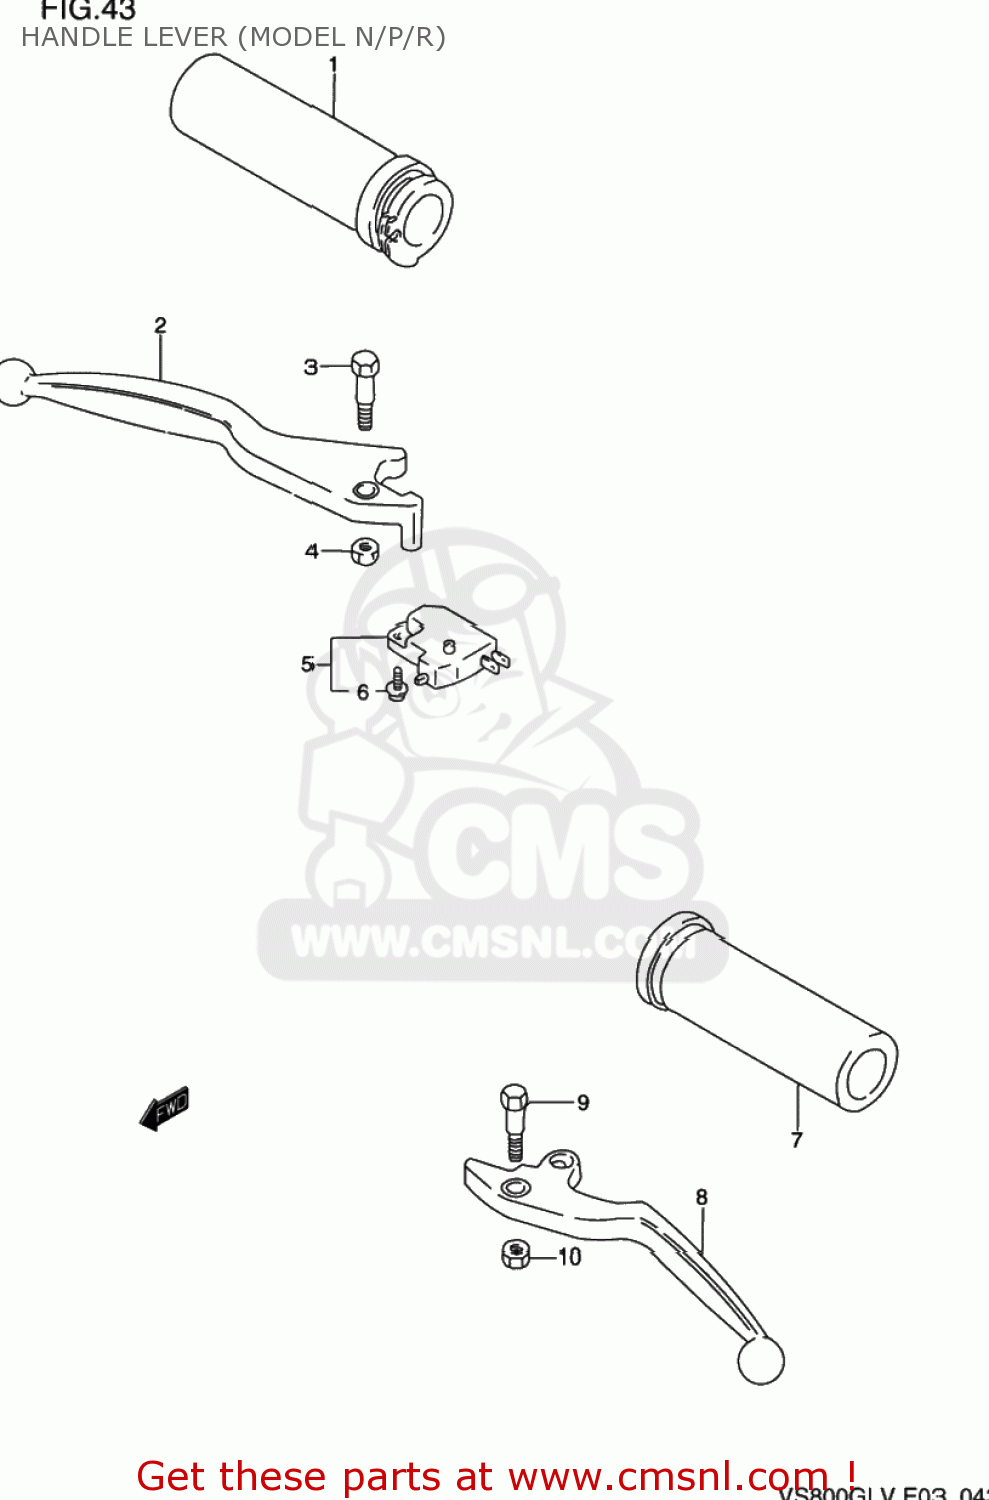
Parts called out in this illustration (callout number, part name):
1	GRIP,THROTTLE
2	LEVER,BRAKE
3	BOLT,LEVER
4	NUT 6MM
5	SWITCH ASSEMBLY,STOP
6	SCREW
7	GRIP,L
8	LEVER,CLUTCH (SILVER)
9	BOLT,LEVER
10	NUT 6MM
